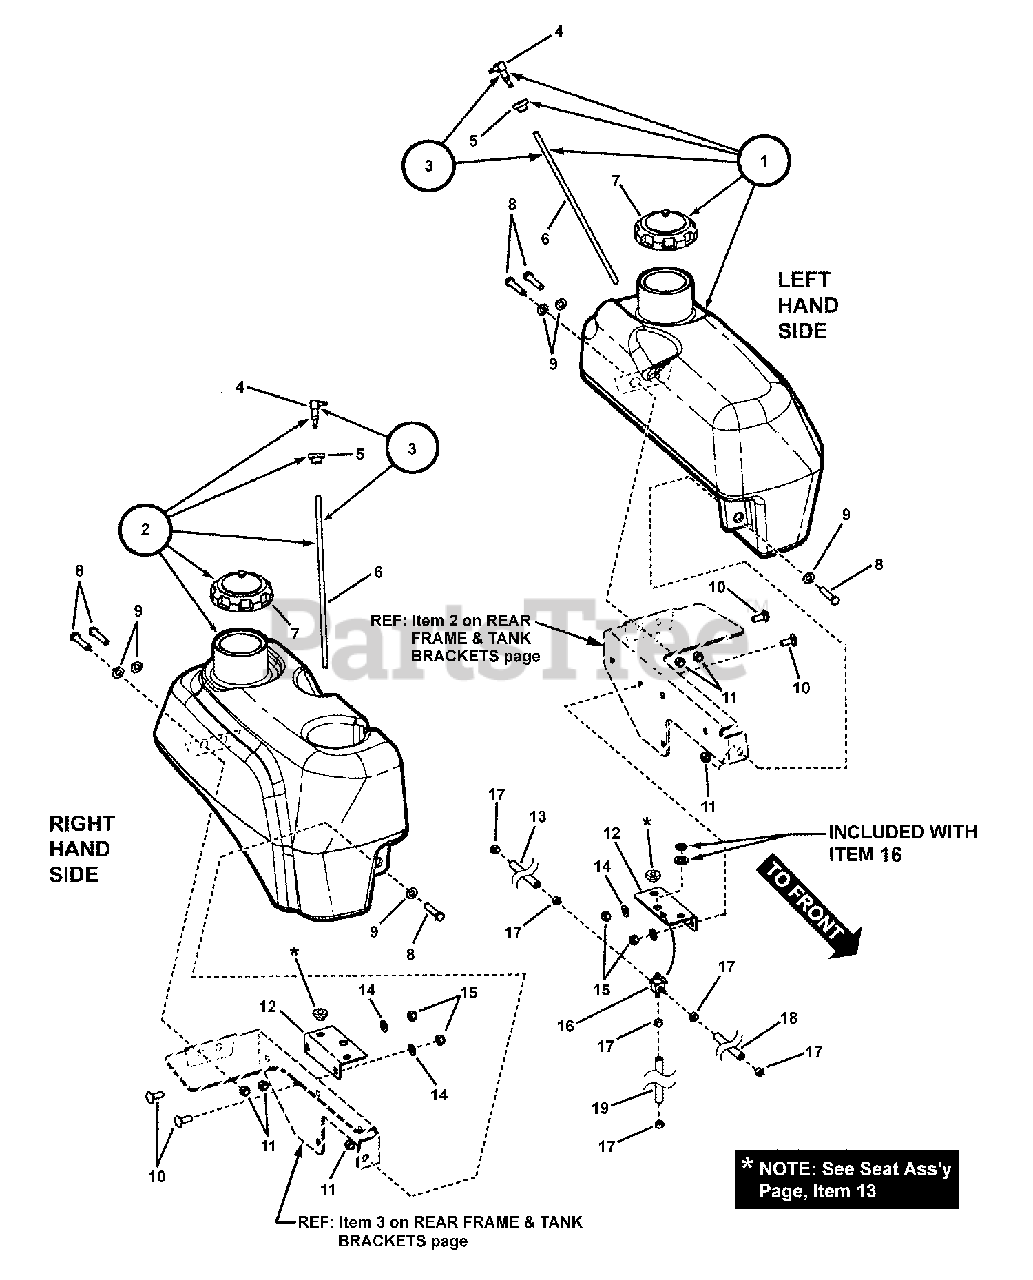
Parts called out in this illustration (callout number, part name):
1	ASSEMBLY, Fuel Tank, Left Hand (Incl. items 3, 5 & 7)
2	ASSEMBLY, Fuel Tank, Right Hand (Incl. items 3, 5 & 7)
3	ASSEMBLY, Fuel Pickup (Incl. items 4 & 6, one each)
4	ELBOW, 90 Degree
7	CAP, 3-1/2" Fuel
8	SCREW, 7/16-14 x 2" Hex Head Cap, GR 5
9	WASHER, 1/2" Flat SAE
10	BOLT, 3/8-16 x 1" Square Neck Carriage GR 5
11	NUT, 7/16-14 HEX NYLON LOCK
12	BRACKET, Valve Mount
13	HOSE, 1/4" I.D. x 1'-8" Long Fuel (L.H.)
14	WASHER, 3/8" Flat
15	NUT, 3/8-16 HEX NYLON LOCK
16	ASSEMBLY, 3-Way Fuel Valve
17	CLAMP, Fuel Hose
18	HOSE, 1/4" I.D. x 3'-7.5" Long Fuel (R.H.)
19	HOSE, 1/4" I.D. x 1'-9" Long Fuel
